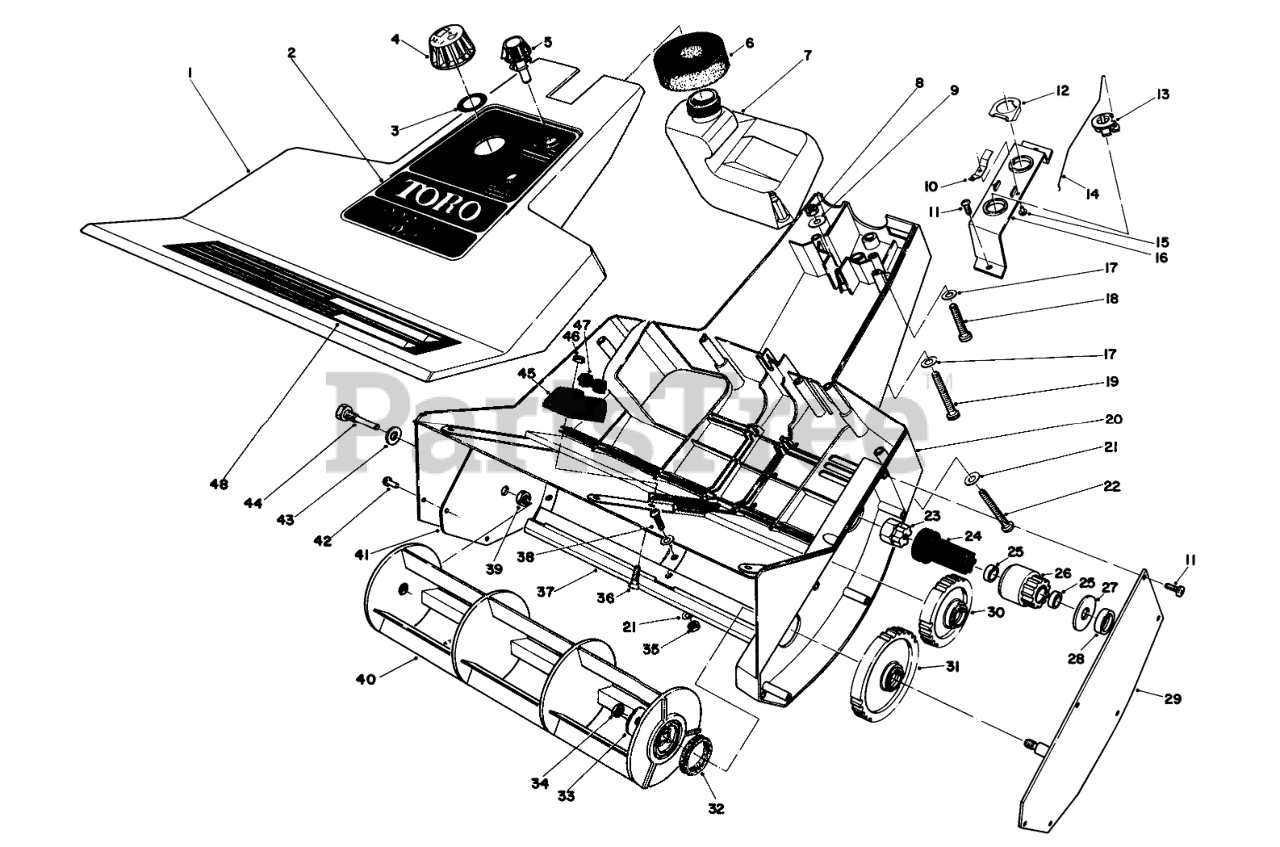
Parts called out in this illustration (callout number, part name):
1	Insert-Shroud Assembly (Incl. Ref. #48)
2	CONTROL DECAL
3	Gasket
4	Gas Cap Assembly (Incl. Ref. #3)
5	Knob-Control
6	FOAM PAD
7	GAS TANK
8	NUT-LOCK, NI
9	WASHER
10	CONTACT SWITCH
11	SCREW-PPH
12	SWITCH ACTUATOR
13	CONTROL
14	CHOKE LINKAGE
15	.125 X 1/8 POP RIVET
16	Bracket-Controls
17	WASHER-FLAT
18	SCREW-HSH
19	SCREW-HSH
20	Housing (Incl. Ref. #41 & 42)
21	WASHER-FLAT
22	MACH SCREW 10-24 2.25 L
23	Adapter-Crankshaft
24	DRIVE COUPLING
26	Gear Assembly-Drive (Incl. Ref. #25)
27	Washer
28	Spacer Gear
29	Gear Carrier Plate
30	Gear Assembly-Idler
31	Gear Assembly-Rotor
32	FELT WASHER
33	WASHER-FLAT
34	NUT-LOCK, NI
35	NUT-LOCK
36	Screw-Machine Slotted Flat Hd.
37	SCRAPER
38	8-32 PH TRUSS HD MS
39	3/8 24 JAM NUT
40	ROTOR
41	Plate Housing Reinforcement
42	RIVET-POP
43	WASHER-FLAT
44	ROTOR PIN
45	Mount-Engine Upper
46	NUT-LOCK, NI
47	Mount-Rubber Isolator
48	Decal-Warning
